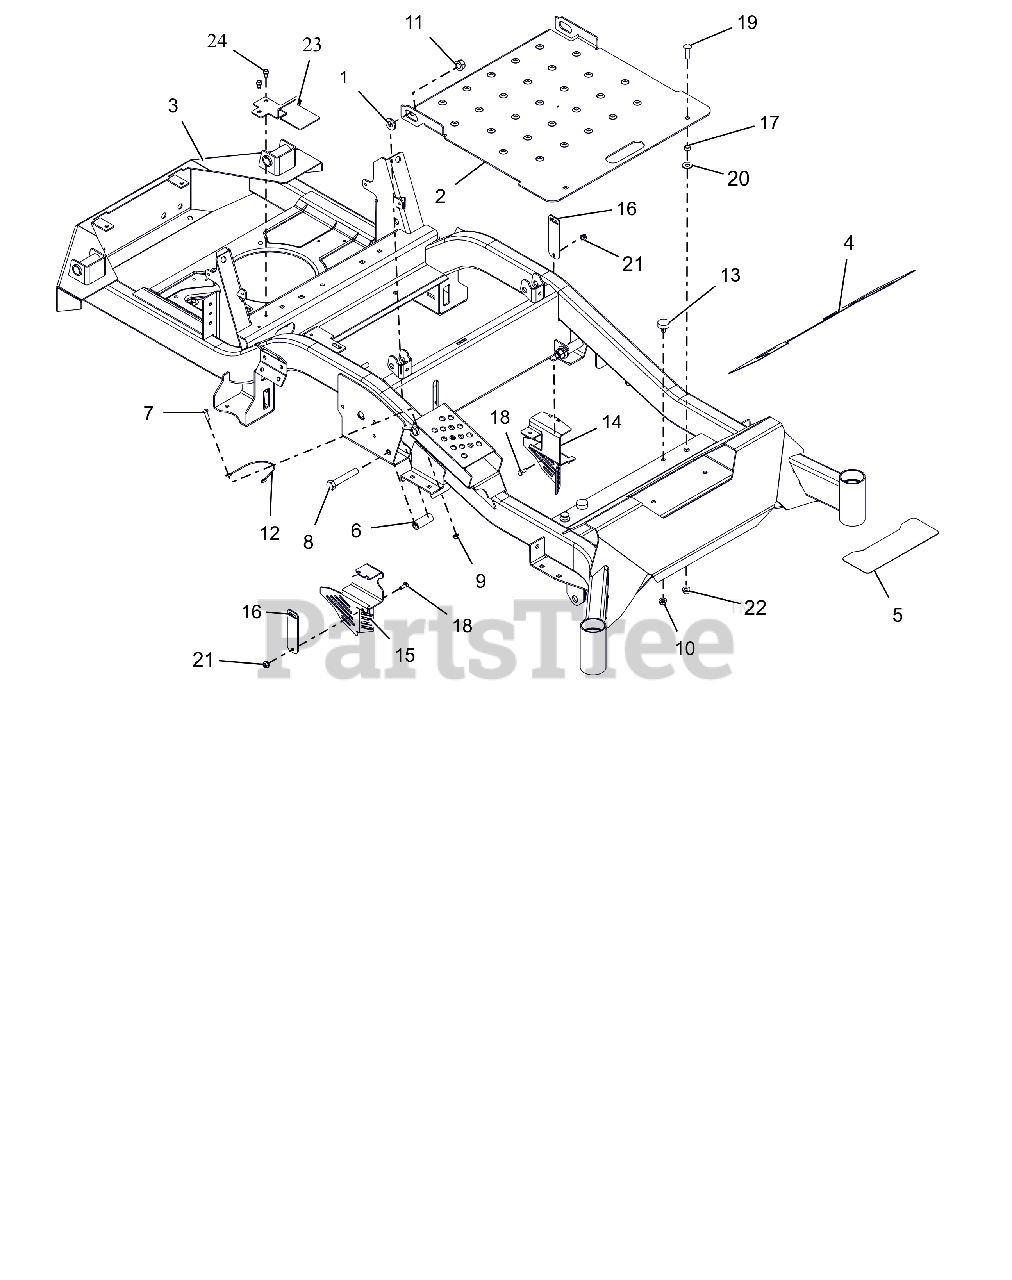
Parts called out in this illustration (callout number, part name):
1	BSHG-FLG .515X.750X.395X1.120
2	PLATE, ACCESS
3	APEX,44-52 FRAME W/SAFETY DECA
4	GRIP, FRONT
5	GRIP, STEP
6	SPACER, .515X.75X1.83
7	@BLT-HEX .25-20X.75 GR5 YWZC
8	@BLT-HEX .50-13X3.00 GR5 YWZC
9	@NUT-LK-NYL-FLG .25-20 YWZC
10	@NUT-SPNLK-FLG .312-18 YWZC
11	@NUT-LK-TOP-FLG .50-13 YWZC
12	CABLE, 12.0 LANYARD, NYLON
13	BUMPER, RUBBER
14	GUARD, TRANSAXLE FAN-LH
15	GUARD, TRANSAXLE FAN - RH
16	BRKT,TRANSAXLE FAN GUARD
17	BSHG-SLV .344 X .500 X .260
18	BLT-HEX .25-20X.63 GR5 YWZC
19	@BLT-RHDSHSQNK.31-18X1.25 G5YZ
20	@WSHR-FL-STL.38X.875X.083 YWZC
21	@NUT-LK-TOP-FLG .25-20 YWZC
22	@NUT-LK-NYL-FLG .31-18 YWZC
23	GUARD, TRANSAXLE FAN RH (BLACK)
24	SCR-TAP .25-20X.50 HWH ZCC
